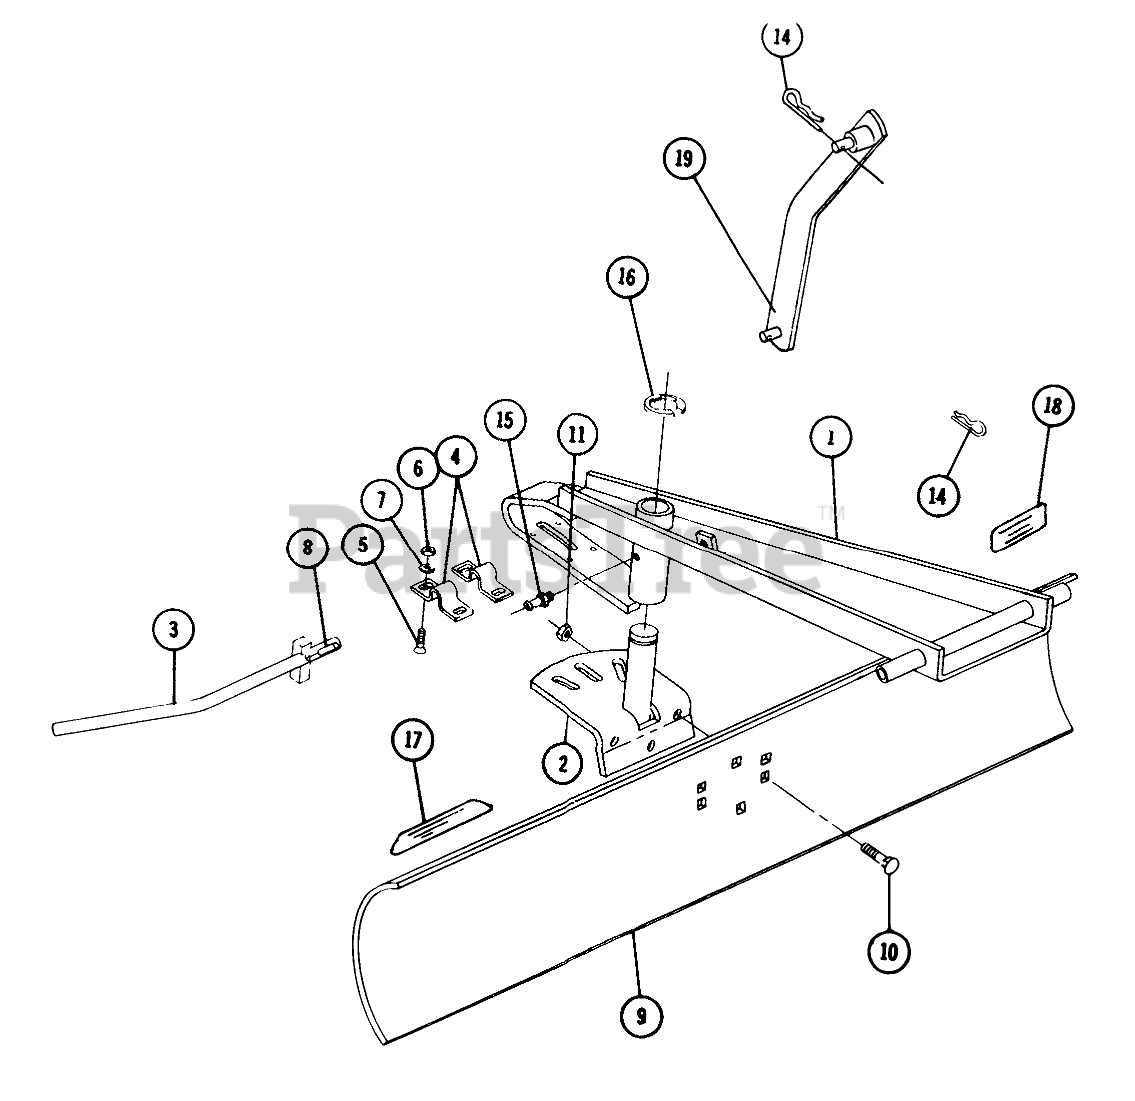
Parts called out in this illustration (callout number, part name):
1	Frame Assembly
2	Blade Support
3	Rod-Angle Adjustment
4	Bracket
5	Screw 1/4-20 x 5/8 Mach. Rd. Hd. Slotted
6	Nut
7	WASHER
8	PIN-ROLL
9	Blade
10	Bolt
11	NUT
13	Pin
14	Hairpin
15	Zerk
16	E RING
17	DECAL-WHEEL HORSE
18	Surfacing-Die Cut
19	Lift Link
